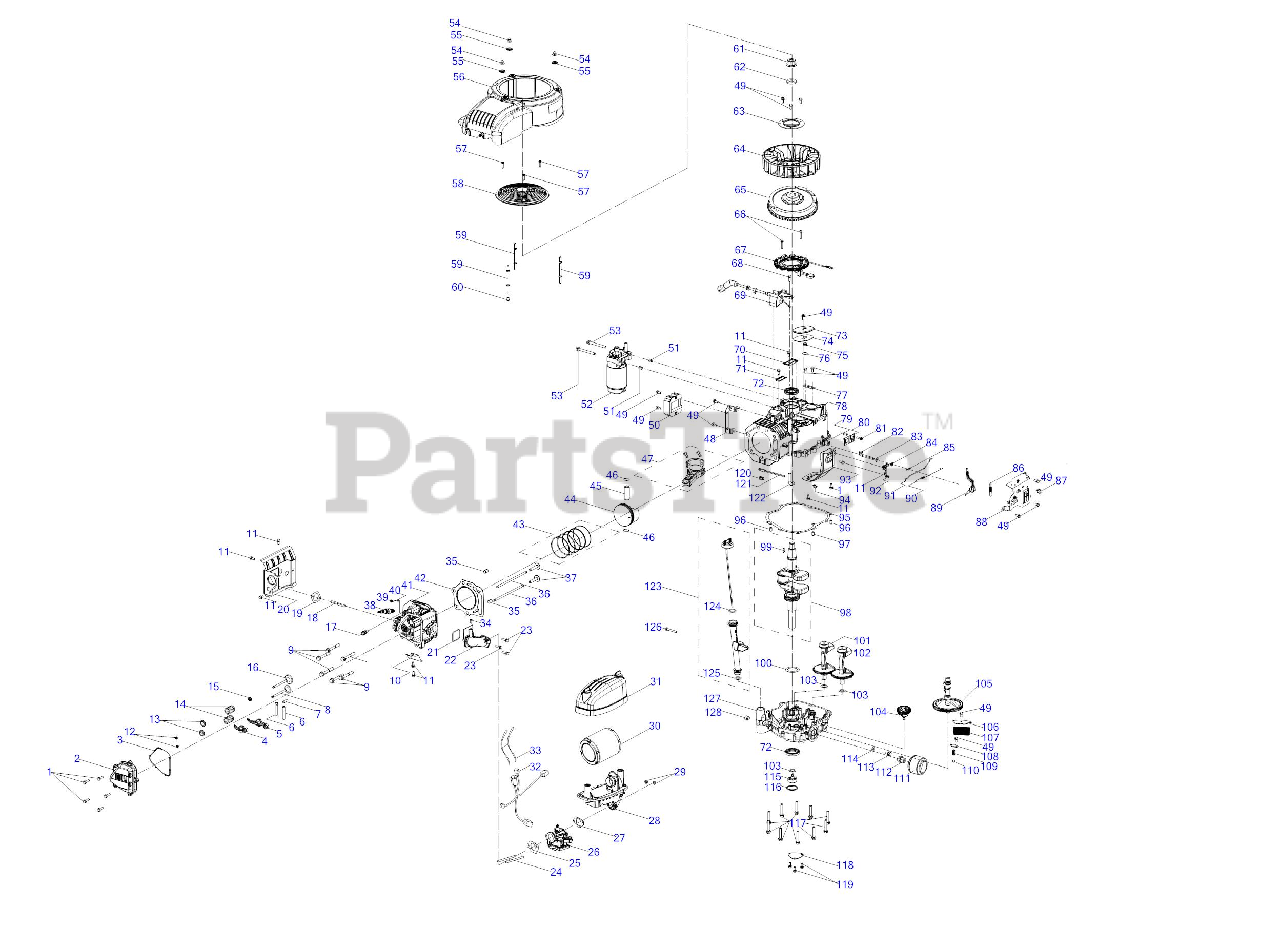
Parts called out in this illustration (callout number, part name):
1	BOLT M6-1 x 25 GR8.8
2	VALVE COVER
3	VALVE COVER GASKET
4	ROCKER ARM
5	ROCKER ARM
6	ROCKER ARM SHAFT
7	CAMSHAFT PIN
8	EXHAUST VALVE
9	BOLT M10-1.25 x 70
10	SHROUD
11	BOLT M6-1 x 12 GR8.8
12	VALVE CAP
13	VALVE SPRING SEAT
14	VALVE SPRING
15	INTAKE VALVE SEAL
16	INTAKE VALVE
17	HOOK BOLT
19	EXHAUST GASKET
20	SHROUD - LEFT SIDE
21	INTAKE PIPE RING
22	INTAKE PIPE
23	BOLT M6 x 22
24	STUD M6-1.00 x 92
25	INTAKE GASKET
26	THROTTLE BODY
27	AIR FLTER GASKET
28	INTAKE MANIFOLD
29	HEX NUT
30	AIR FILTER W/PREFILTER
31	AIR FILTER COVER
32	CABLE ASSEMBLY
33	CABLE TIE - 3 x 150
34	SELF TAPPING SCREW 4.8 x 16
35	PIN 12X16
36	SINGLE PUSH ROD
37	TAPPET
38	SPARK PLUG
39	BOLT M5-.8 x 10
40	FLAT WASHER: 5.3 x 10 x 1
41	CYLINDER HEAD
42	CYLINDER HEAD GASKET
43	PISTON RING SET
44	PISTON
45	PISTON PIN
46	PISTON PIN SNAP RING
47	CONNECTING ROD ASSEMBLY
48	REGULTOR BRACKET
49	BOLT M6-1 x 14 GR8.8
50	REGULATOR
51	DOWEL PIN
52	ELECTRIC STARTER
53	BOLT M8-1.25 x 80
54	ACORN NUT
55	WASHER
56	ACORN NUT
57	BOLT 5.5 x 25
58	DEBRIS SHIELD
60	BUSHING
61	NUT M20 x 1.5
62	WASHER 20.5 x 5 x 40
63	VANE PLATE
64	COOLING FAN
65	FLYWHEEL
66	BOLT M5 x 28
67	CHARGING COIL
68	BOLT M6-1 x 18 GR8.8
69	IGNITION COIL
70	WIRE PLATE
71	BREATHER SCREEN
72	OIL SEAL 38 x 58 x 8
73	BREATHER COVER
74	BREATHER COVER GASKET
75	BREATHER VALVE SPRING
76	BREATHER VALVE
77	BRACKET
78	CRANKCASE
79	LIMIT HOSE
80	LIMIT PLATE
81	BOLT M5 x 18
82	GOVERNOR GEAR SHAFT
83	WASHER 8 x 0.8 x 16
84	GOVERNOR SEAL
85	GOVERNOR SHAFT CLIP
86	GOVERNOR SPRING
87	FUEL LINE SUPPORT CLAMP
88	GOVERNOR GEAR BRACKET ASSEMBLY
89	GOVERNOR LEVER
90	THROTTLE LINKAGE
91	THROTTLE LINKAGE
93	SHROUD - RIGHT
94	PLASTIC SUPPORT CLAMP
95	CRANKCASE COVER GASKET
96	DOWEL PIN
97	DOWEL PIN
98	CRANKSHAFT ASSEMBLY
99	FLYWHEEL KEY
100	WASHER 38.3 x 54 x 1
101	BALANCE SHAFT LEFT
102	BALANCE SHAFT RIGHT
103	WASHER 17.2 x 26 x 1
104	GOVERNOR GEAR ASSEMBLY
105	CAMSHAFT
106	FILTER COVER
107	FILTER SCREEN
108	PRESSURE RELEASE COVER
109	PRESSURE RELEASE SPRING
110	STEEL BALL
111	ENGINE OIL FILTER
112	SCREW JOINT OIL FILTER ADAPTER
113	BOLT M8 x 15
114	OIL DRAIN PLUG WASHER
115	OIL PUMP ASSEMBLY
116	GASKET
117	BOLT M8 x 45
118	OIL SEPARATOR
119	SCREW M6-1 x 16
120	TEMPERATURE SENSOR CLIP
121	TEMPERATURE SENSOR
122	VENTING HOSE
123	DIPSTICK ASSEMBLY
124	O-RING
125	O-RING
126	BOLT M6-1 x 45 CL5.8
127	CRANKCASE COVER
128	ENGINE PLUG 3/8 NPT
